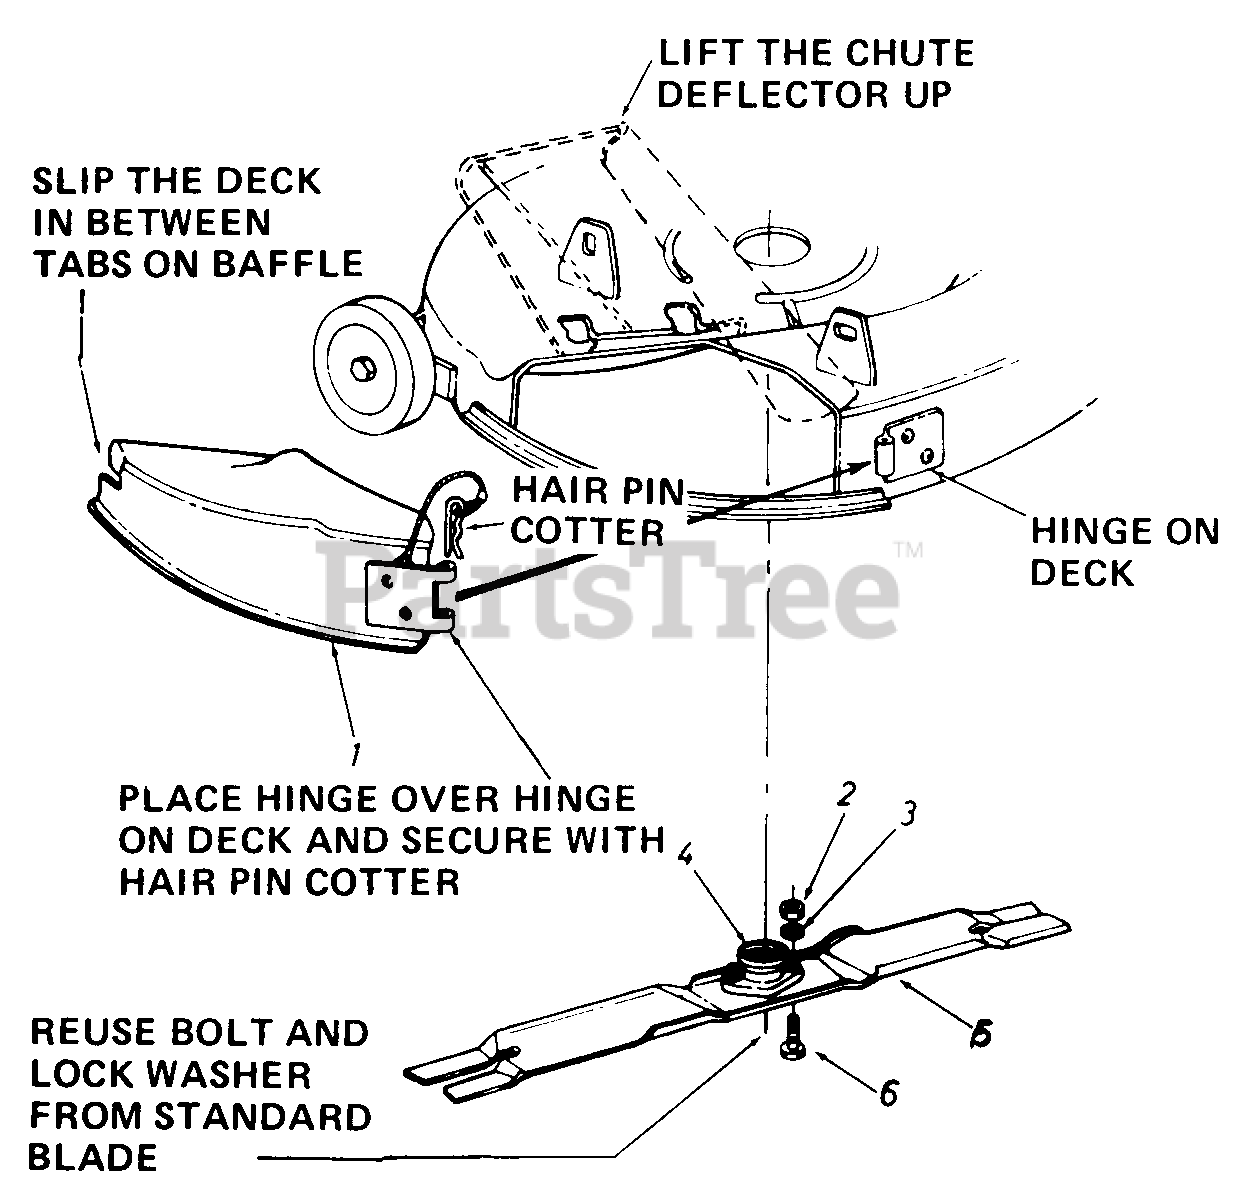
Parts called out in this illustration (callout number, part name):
1	30" Mulching Baffle Ass'y.
2	Hex Nut 5/16-24 Thd.*
3	L.-Wash. 5/16" I.D.*
4	Kit-Blade Adapter Ass'y.
5	30" Mulching Blade
6	Hex Bolt 5/16-24 x 1.0" Lg. H.T.
